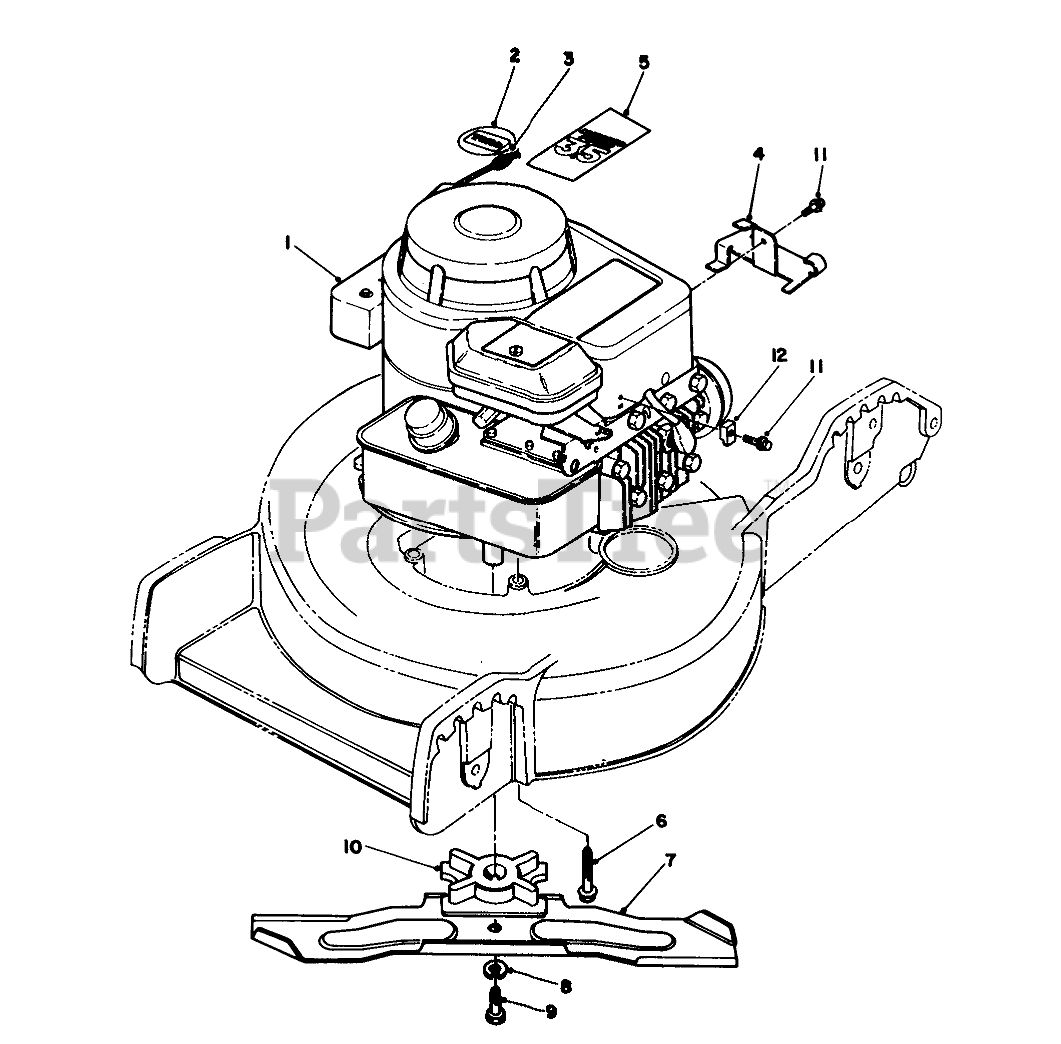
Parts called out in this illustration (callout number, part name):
2	DECAL
3	STOP-ROPE
4	CABLE BRACKET
5	DECAL - ENGINE
6	3/8-16X2 TAPTITE HEX HD
7	Blade-18"
8	WASHER-LOCK
9	SCREW-HH
10	BLADE RETAINER
11	CLAMP SCREW F/W ENGINE
12	CASING CLAMP F/W ENGINE
